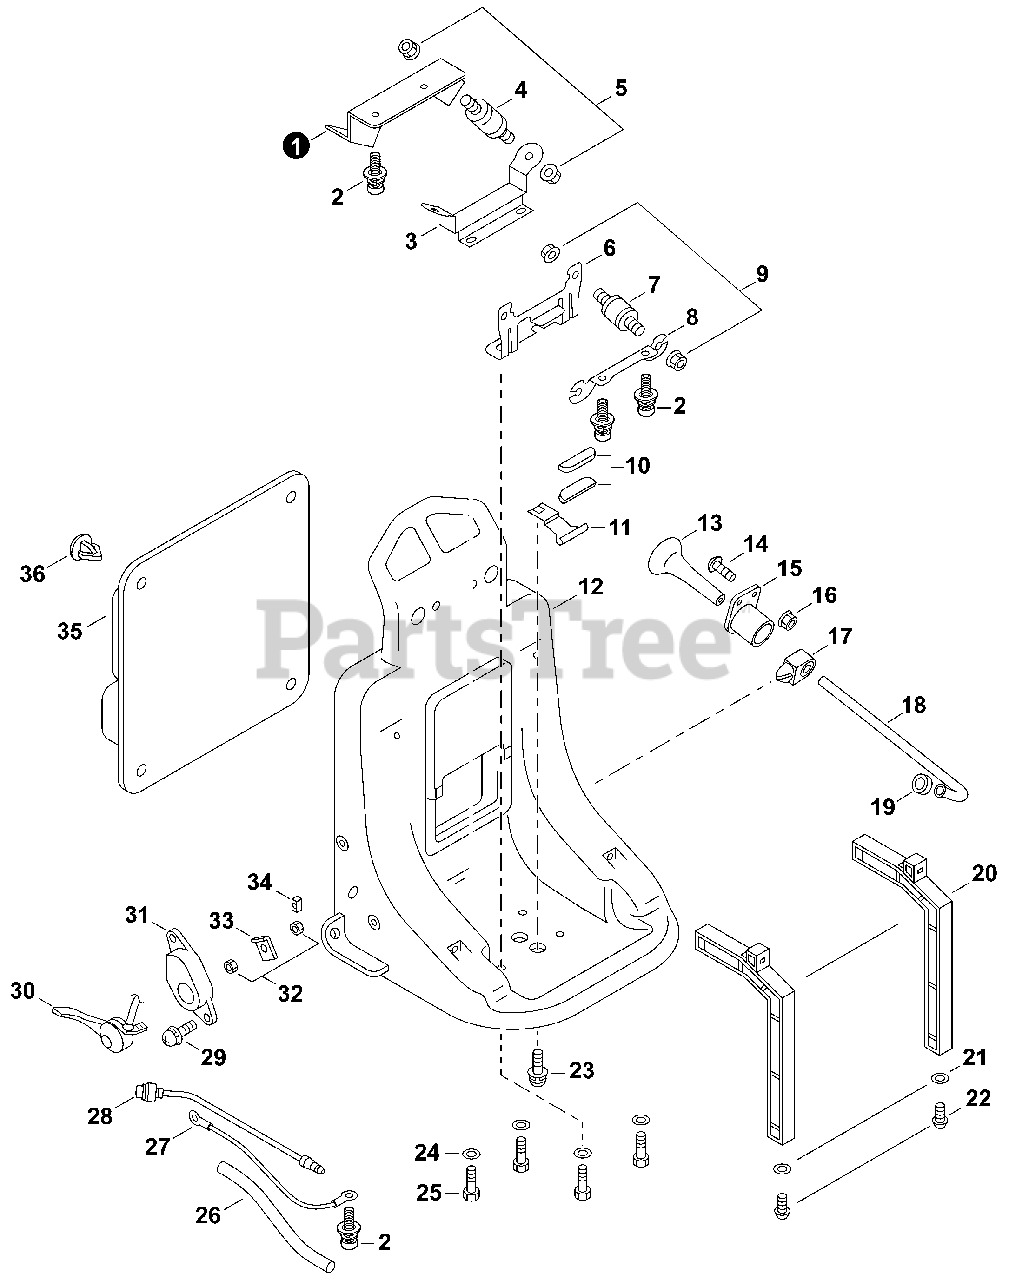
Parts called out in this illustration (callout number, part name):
1	PLATE, ANGLE
2	SCREW 5x12
3	PLATE, ANGLE
5	NUT, FLANGE M6
6	BRACKET, FUEL TANK
8	BRACKET, ENGINE
9	NUT, FLANGE M5
10	CUSHION, FUEL TANK
11	BRACKET, FUEL TANK
12	FRAME, BACKPACK
13	GRIP, STARTER
14	SCREW 4x14
15	BRACKET, HANDLE
16	NUT, FLANGE
17	GUIDE, ROPE
18	GUIDE, ROPE
19	CUSHION
20	SUPPORT, CHEMICAL TANK
22	SCREW, TAPPING
23	SCREW 6x15
25	BOLT 6x16
26	PROTECTOR, TUBE
28	SWITCH, STOP
29	SCREW 5x20
30	CONTROL, THROTTLE
31	BRACKET, THROTTLE
33	PLATE, FIXED
35	CUSHION, BACKPACK
